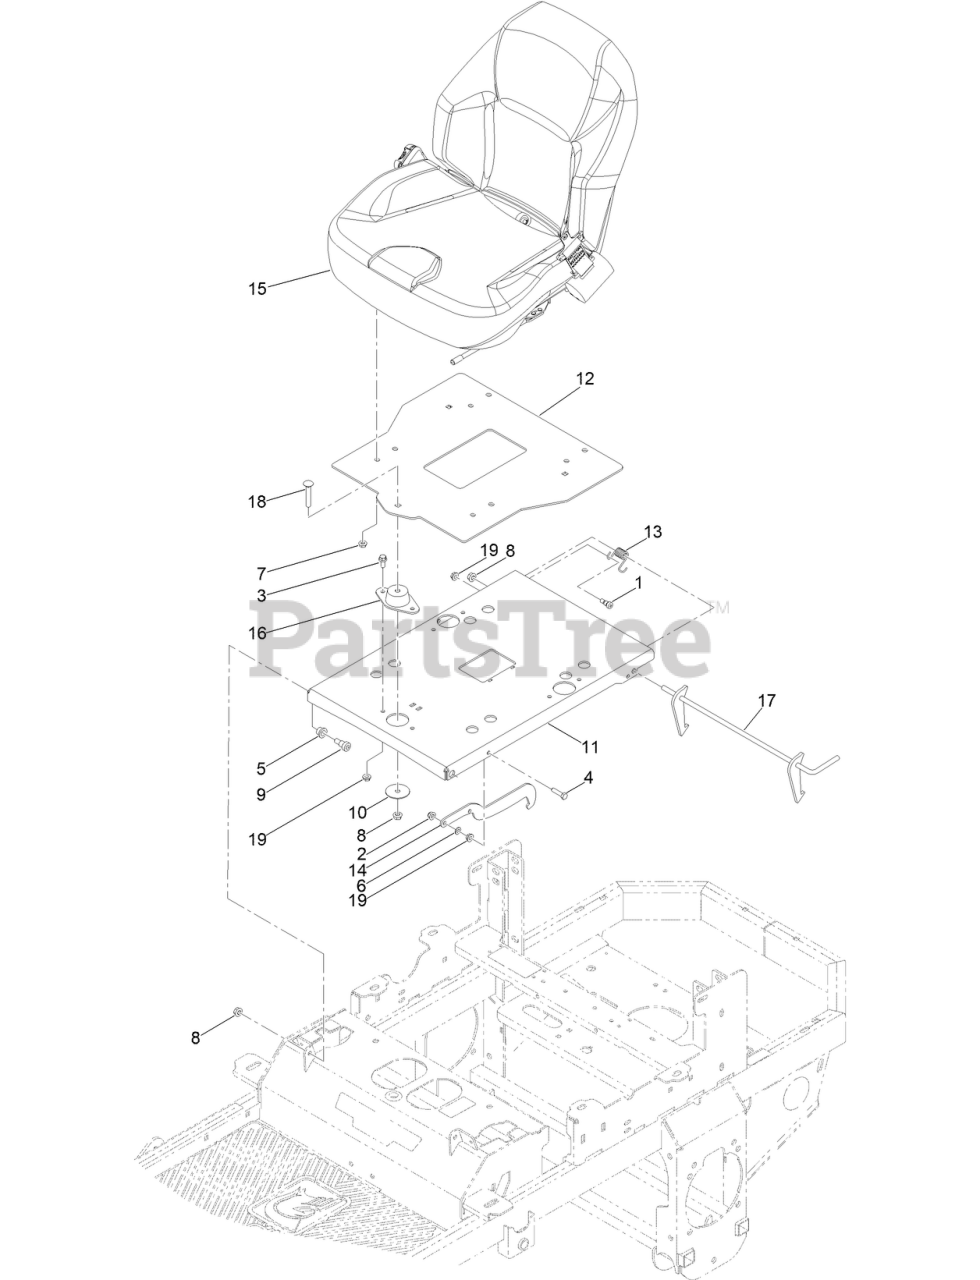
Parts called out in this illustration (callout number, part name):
1	SCREW-HSH
2	NUT-HF, NI
3	SCREW-HHF
4	SCREW-HH
5	1/2IN ID X 5/8IN OD X 1/2IN FLANGE BUSH
6	.312IDX.625ODX.062 THK THRUST BRG OI BRZ
7	5/16-18 NYLON INSERT FLANGE L/NUT ZC
9	1/2 X 1/2 SOCKET SHOULDER BOLT ZC YELLOW
10	3/8 X 2IN OD FENDER WASHER YZ
11	2019 UPGRADE SEAT BASE PLATE PAINT
12	2019 UPGRADE SEAT PLATE PAINT
13	MWR SEAT LATCH SPRING
14	MWR SEAT LATCH HOOK PAINT
15	2020 RZ-HD SEAT
16	FLOATING SEAT DAMPER-STIFFER
17	MWR SEAT LATCH RELEASE ASSY ABC
18	SCREW-CARR
19	NUT-HF
